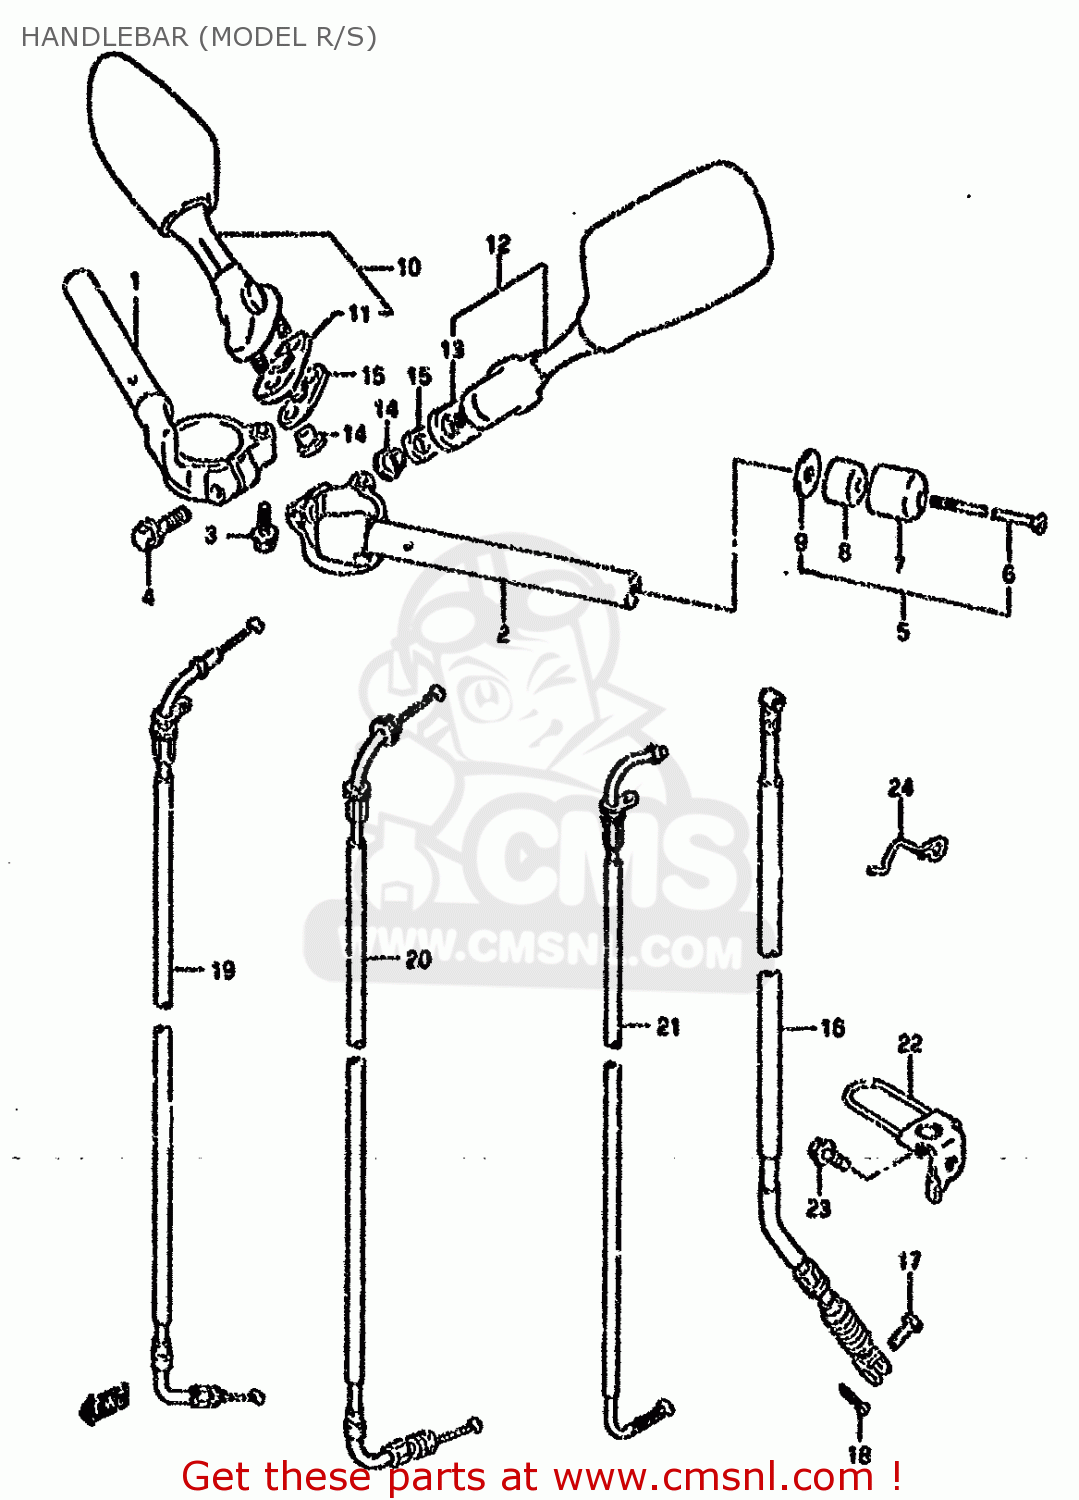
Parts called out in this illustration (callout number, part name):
1	HANDLEBAR,RH
2	HANDLEBAR,L
3	BOLT
4	BOLT(8X30)
5	BALANCER SET,HANDLEBAR
6	SCREW
7	CAP,BALANCER
8	BALANCER,HANDLE
9	SPACER,BALANCER
10	MIRROR ASSEMBLY,REAR VIEW
11	GASKET,RR VIEW MIRROR,R (NAS)
12	MIRROR ASSEMBLY,REAR VIEW
13	GASKET,RR VIEW MIRROR,L (NAS)
14	NUT,RR VIEW MIRROR
15	CUSHION,RR VIEW MIRRORR
16	CABLE ASSY,CLUTCH
17	PIN(L:15)
18	PIN
19	CABLE ASSY,THROTTLE NO.1
20	CABLE ASSY,THROTTLE NO.2
21	CABLE,STARTER
22	GUIDE,CABLE
23	BOLT
24	GUIDE,CLUTCH CABLE
25	CABLE ASSY,THROTTLE NO.2
26	CABLE,STARTER
27	CLAMP
28	CLAMP(L:235)
29	CUSHION,FRAME COVER
